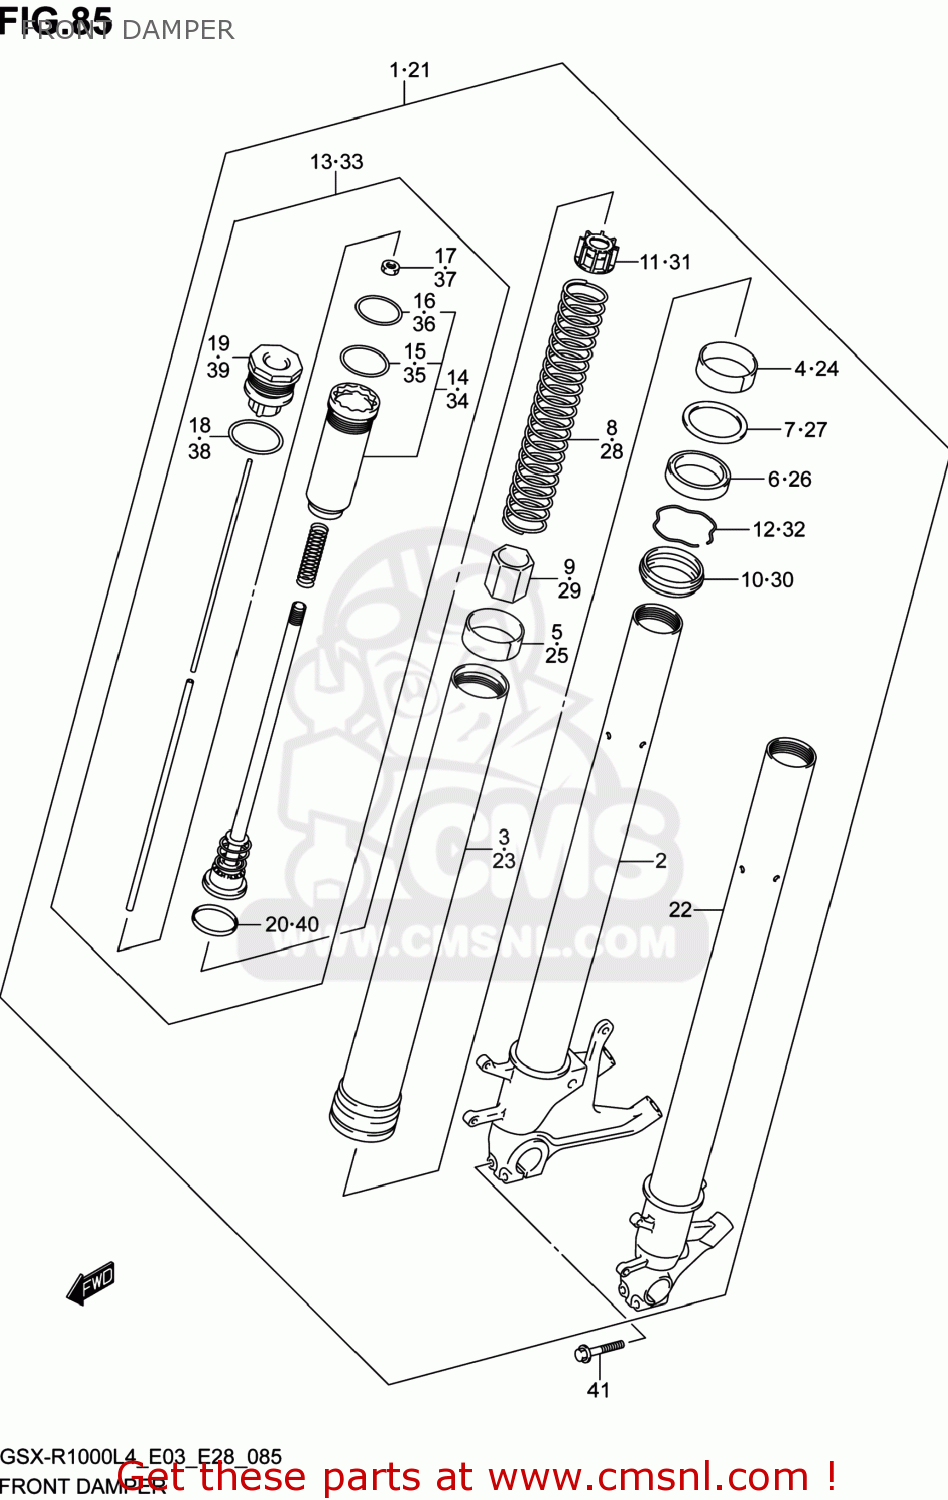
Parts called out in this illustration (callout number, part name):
1	DAMPER ASSY,FR FORK,R
2	TUBE,INNER,R
3	TUBE,OUTER
4	BUSH,GUIDE
5	BUSH,SLIDE
6	SEAL,OIL
7	SPACER,SEAL
8	SPRING
9	COLLAR,SPRING
10	SEAL,DUST
11	COLLAR,SPRING
12	CIRCLIP,FORK OIL SEAL
13	ROD,PISTON
14	CASE,ROD GUIDE
15	RING,PISTON
16	O RING
17	NUT
18	O RING
19	BOLT
20	RING,PISTON
21	DAMPER ASSY,FR FORK,L
22	TUBE,INNER,L
23	TUBE,OUTER
24	BUSH,GUIDE
25	BUSH,SLIDE
26	SEAL,OIL
27	SPACER,SEAL
28	SPRING
29	COLLAR,SPRING
30	SEAL,DUST
31	COLLAR,SPRING
32	CIRCLIP,FORK OIL SEAL
33	ROD,PISTON
34	CASE,ROD GUIDE
35	RING,PISTON
36	O RING
37	NUT
38	O RING
39	BOLT
40	RING,PISTON
41	BOLT
